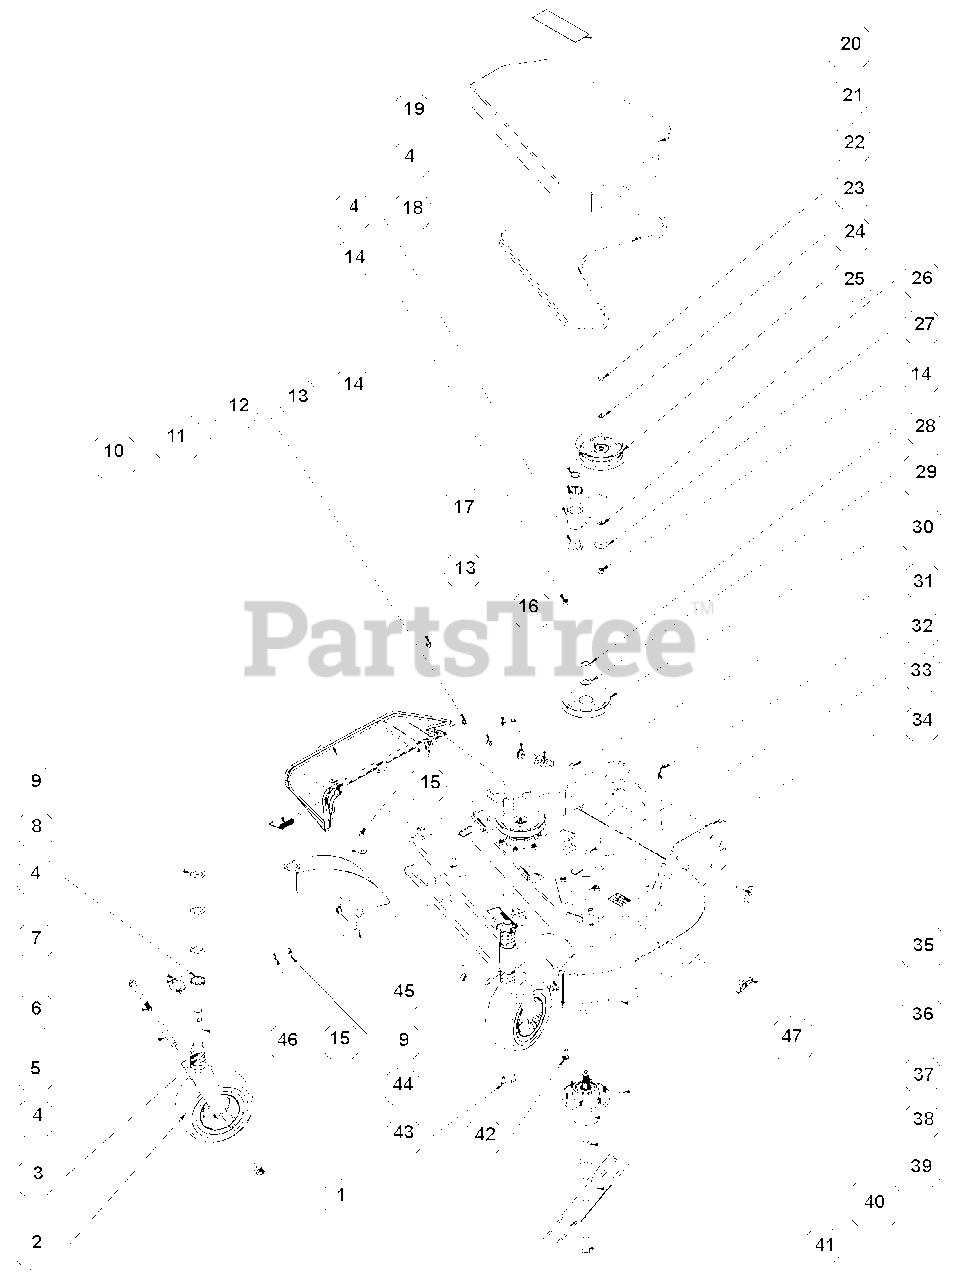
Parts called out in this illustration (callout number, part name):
1	Locknut, .50-13 Nyloc
2	Assembly, Wheel and Tire 9 x 3.5
3	Bushing, 1.03 x 1.50 x .179
4	Bearing, Flange 1.00 x 1.25 x 1.00
5	Tube, Caster Axle
6	Bolt, .50-13 x 5.50 Hex 5
7	Pin, LNC .438 x 2.00
8	C-Spacer, 1.00 x 1.77 x .500
9	Washer, .375 Regular Flat
10	Spring, Discharge Chute
11	Chute, Discharge Assembly
12	Retainer
13	Locknut, .38-16 Crown
14	Locknut, .38-16 Nyloc
15	Locknut, .4375-14 Crown
16	Spring, COM 1.22 x .162 x 2.50
17	Keeper, Spring
18	Weldment, Idler Arm
19	Snap Ring, 1.00 x .042 External
20	Decal, 9" EverRide Logo
21	Weldment, 36" Deck Shield EverRide
22	Belt, HB 74.3 Elbow AMD OHR
23	Bolt, .38-16 x 2.50 Hex 5
24	Washer, .406 x .813 x .065 Flat
25	Pulley, Flat 5.00X.375 W/BRG
26	Bushing, .380 x 1.00 x .410
27	Washer, .375 x 1.50 x .063 Flat
28	Locknut, .75-16 Crown
29	Washer, .75 x 1.3125 x .120
30	Pulley, Spline Spindle LSE
31	Nut, .38-16 Standard Hex 5
32	Trim, 1/4" Trim-Lok Edge
33	J-Bolt, .38-16 x 7.88
34	Weldment, Idler Pivot Mount
35	Bolt, Hex .6250-11 1.5" Grade 8
36	Knob, .38-16 Insert
37	Bolt, .38-16 x .750 Round Head Square Neck
38	Assembly, Spindle Housing
39	Washer, .630 x 1.50 x .250 Flat
40	Blade, 18.000 x .80 Lift
41	Bolt, .625-11 x 2.00 Hex 8
42	Bolt, .38-16 x 1.00 Round Head Square Neck
43	Bolt, .38-16 x .750 Hex 5
44	Bolt, .4375-14 x 1.25 Round Head Square Neck
45	Weldment, Caster Support w/EverRide Paint
46	Weldment, Caster Yoke w/EverRide Paint
47	Assembly, EverRide 36" Deck with Decal
